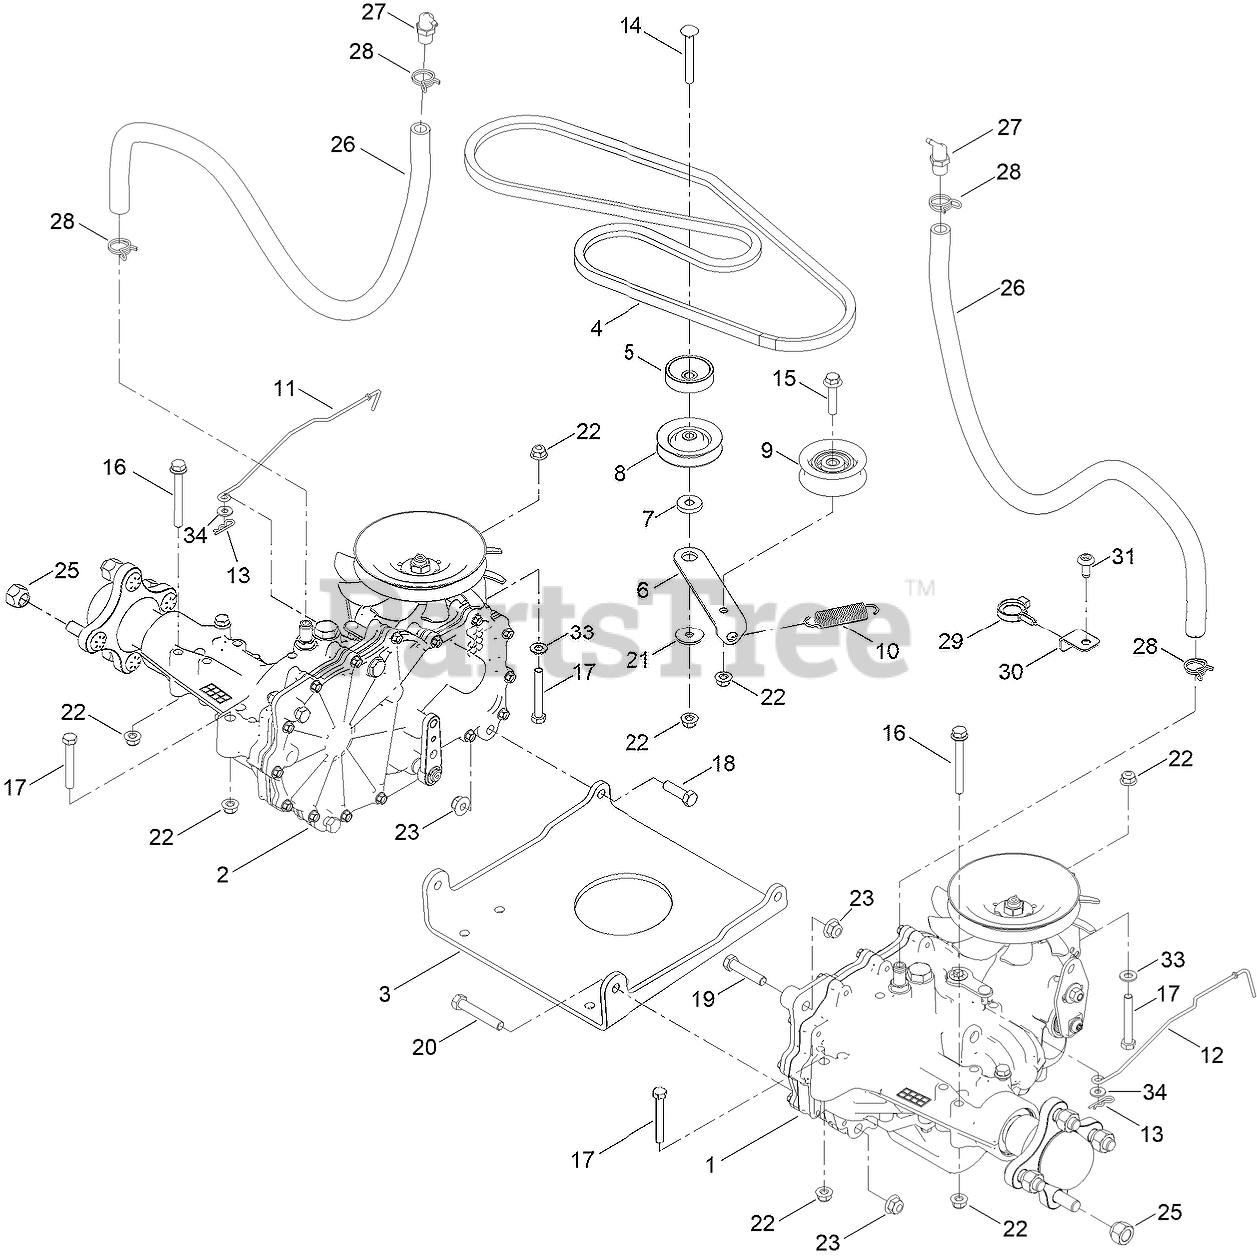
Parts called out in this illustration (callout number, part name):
1	LH HYDRO TRANSMISSION ASM
2	RH HYDRO TRANSMISSION ASM
3	PLATE- HYDRO
4	V-BELT
5	SPACER
6	ARM-IDLER
7	SPACER-IDLER ARM
9	PULLEY-IDLER, FLAT
10	SPRING-PEDAL, RETURN
11	ROD-BYPASS, RH
12	ROD-BYPASS, LH
14	SCREW-CARR
15	SCREW-HHF
16	SCREW-HHF
17	SCREW-HH
18	SCREW-HH
19	SCREW-HH
20	SCREW-HH
21	WASHER-PIVOT
22	NUT-HF, NI
23	NUT-HF, NI
25	NUT-LUG
26	HOSE-HYDRO
27	BREATHER KIT
28	CLAMP-HOSE
29	CLAMP-HOSE
30	MOUNT-BRACKET
33	WASHER-PLAIN
34	WASHER
